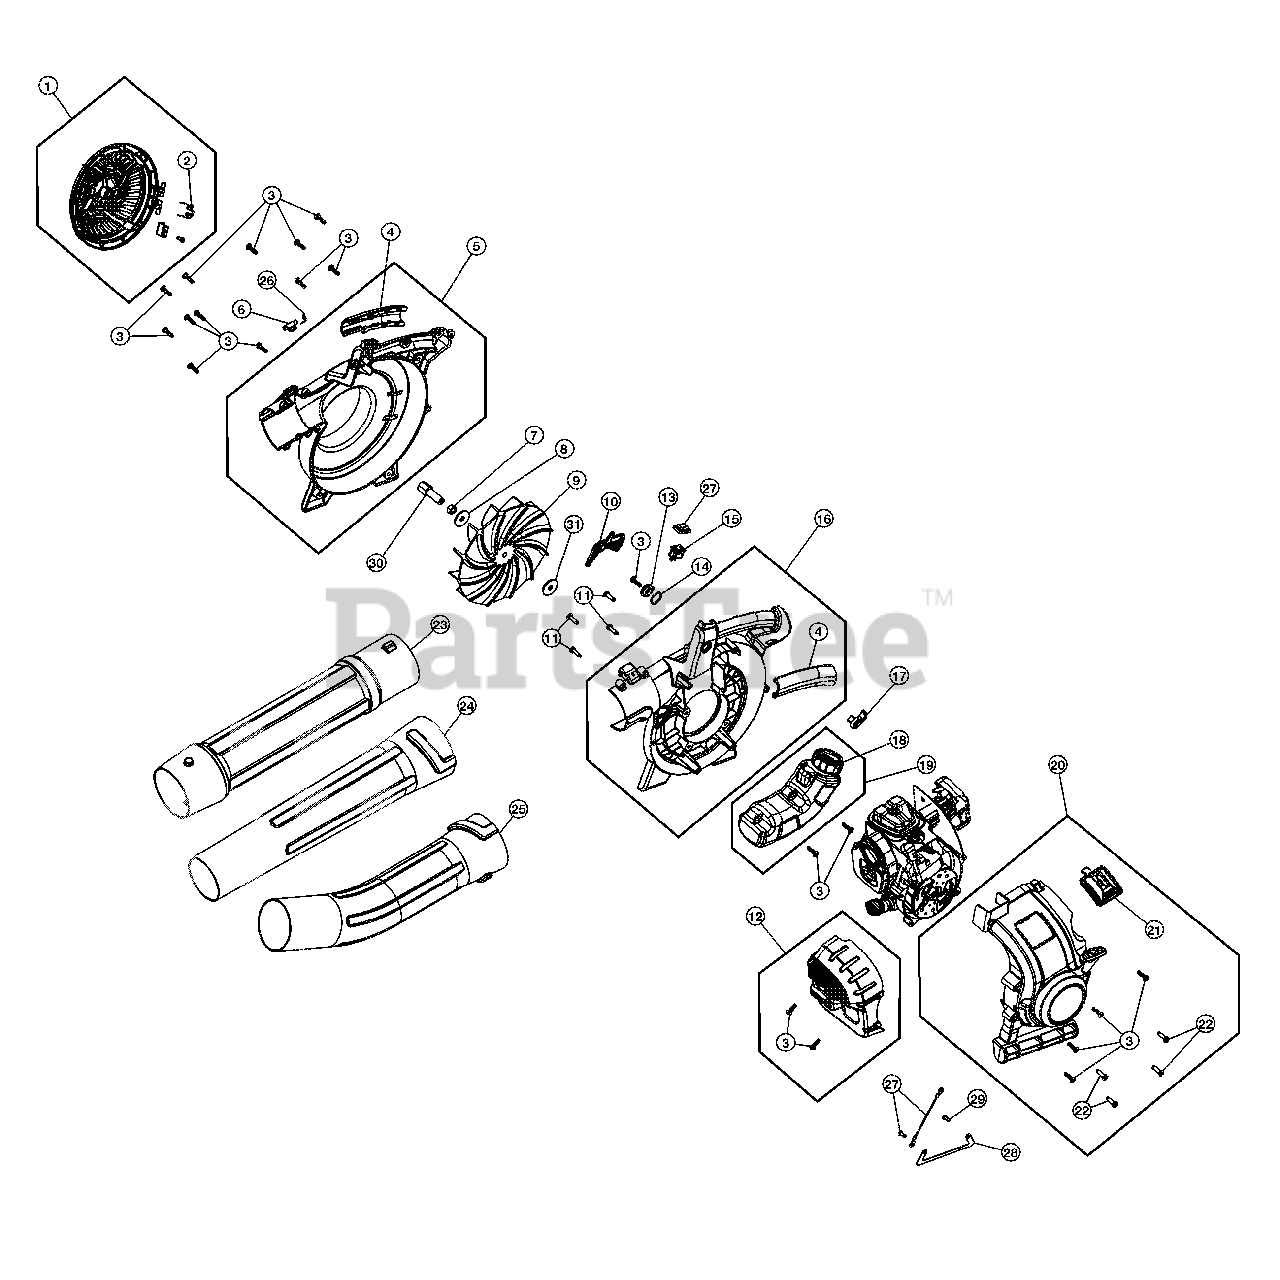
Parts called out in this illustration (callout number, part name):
1	Intake Cover Assembly
2	Spring
4	Handle Grips
5	Impeller Housing (Incl. 4)
6	Latch Tube
8	Washer
9	Impeller
10	Throttle Trigger
11	Screw
12	Muffler Cover (Incl. 3)
13	Inner Trigger Lock
14	Wavey Washer
16	Impeller Housing (Incl. 4)
17	Outer Trigger Lock
18	Fuel Cap
19	Fuel Tank Assembly (Incl. 18)
20	Engine Cover Assembly (Incl. 3, 21 & 22)
21	Spark Plug Cover
23	Upper Tube
24	Lower Tube
25	Flare Tube
26	Latch Spring
27	Wire Ground
28	Strap Ground
29	Screw
30	Adapter
31	Spacer
